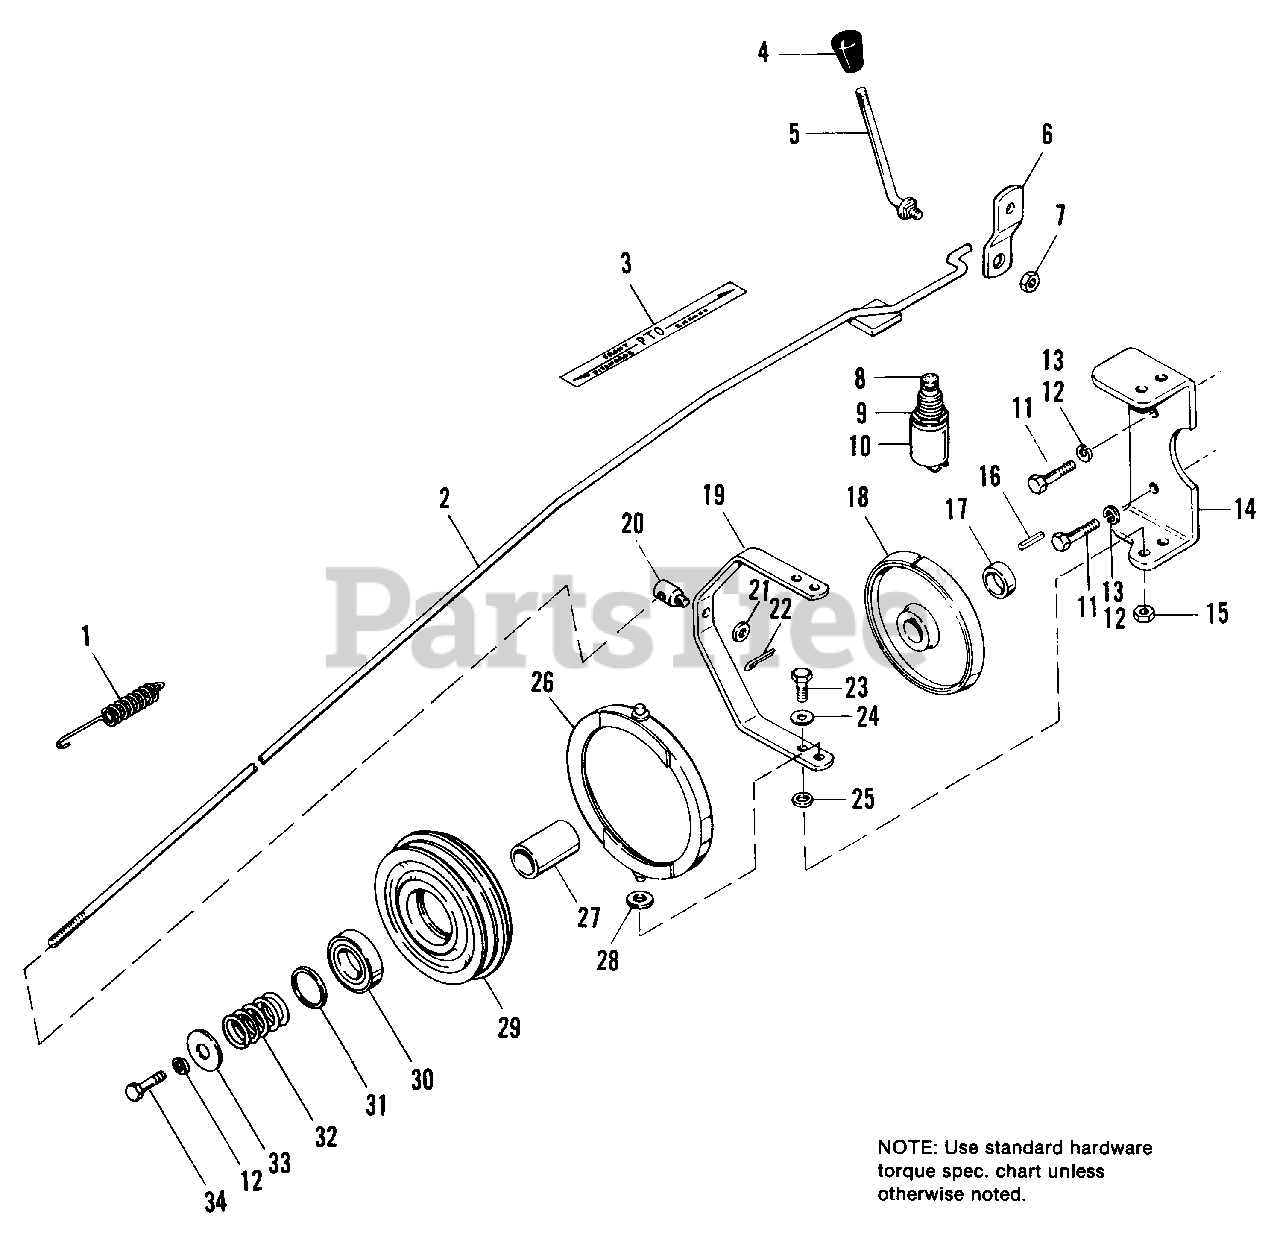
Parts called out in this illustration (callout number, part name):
2	ROD ASSY., Clutch
4	KNOB
5	HANDLE, Clutch Control
6	ARM, P.T.O.
7	LOCKNUT, Hex, 3/8-16
8	BOOT, Rubber
9	NUT, Special
10	SWITCH, Safety
11	CAPSCREW, Hex, 5/16-18 x 1 (Briggs engine only)
11	CAPSCREW, Hex, 3/8-16 x 3/4 (Kohler engine only)
12	LOCKWASHER, 3/8 (Qty. 1 used on Briggs only)
12	LOCKWASHER, 7/16 (Kohler engine only)
13	LOCKWASHER, 5/16 (Briggs engine only)
15	LOCKNUT, Hex, 5/16
16	KEY, Hi-Pro
17	SPACER (Briggs engine only)
18	PLATE ASSY., Clutch (Briggs engine only)
19	FORK, Clutch
21	WASHER, Plain, 5/16
22	COTTER PIN, 3/32 x 5/8
23	CAPSCREW, Hex, 5/16-18 x 3/4
24	WASHER, Plain, 1/4
26	SUPPORT ASSY., Brake
27	SLEEVE (Briggs engine only)
30	BEARING, Ball
31	RING, Backing
34	CAPSCREW, Hex, 3/8-14 x 1-3/4 (Briggs engine only)
34	CAPSCREW, Hex, 7/16-20 x 2 (Kohler engine only)
